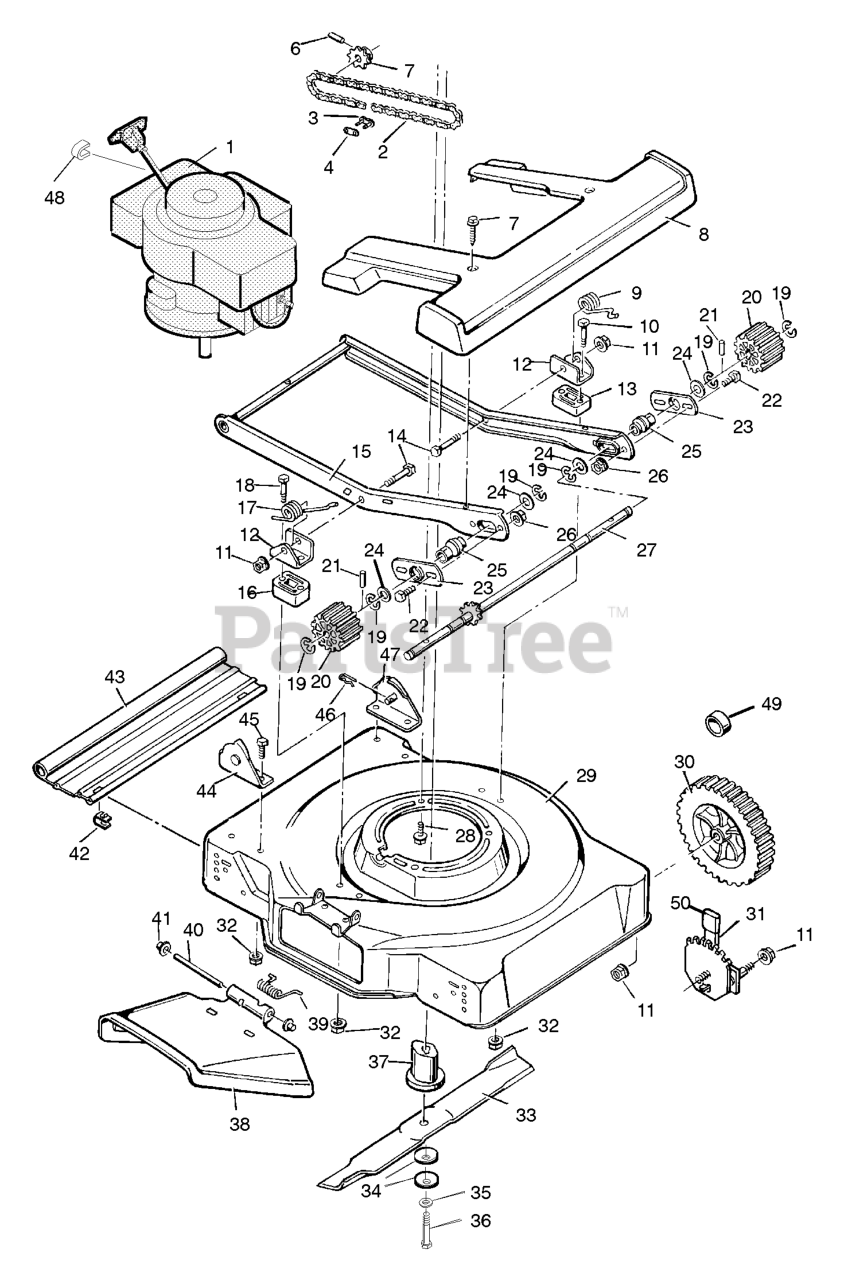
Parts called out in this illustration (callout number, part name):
1	Engine *
3	Master Link
5	Sprocket, Drive
6	Pin, Spring
7	Screw, Tapping
8	Guard, Pinion
9	Spring, Left Torsion
10	Bolt, Hex
11	Locknut, Flange
12	Bracket, Drive Arm
13	Spacer, Left
14	Bolt, Hex
15	Drive Arm Assembly
16	Spacer, Right
17	Spring, Right Torsion
18	Bolt, Hex
19	Retainer Ring
20	Drive Pinion
21	Spring Pin
22	Bolt, Hex
23	Retainer, Bearing
25	Bearing
26	Locknut, Flange
27	Drive Shaft & Sprocket
28	Bolt, Engine
29	Housing
30	WHEEL & TIRE ASSEMBLY, White, 8"
31	Height Adjuster
32	Locknut, Flange
34	Washer, Belleville
37	Blade Adapter
38	Chute Deflector
39	Spring, Torsion
40	Pin, Pivot
41	Push On Cap
42	Retainer
43	Deflector, Rear
44	Bracket, Right Handle
46	Pin, Hair
47	Bracket, Left Handle
48	Stop, Rope
49	Hub Cap
